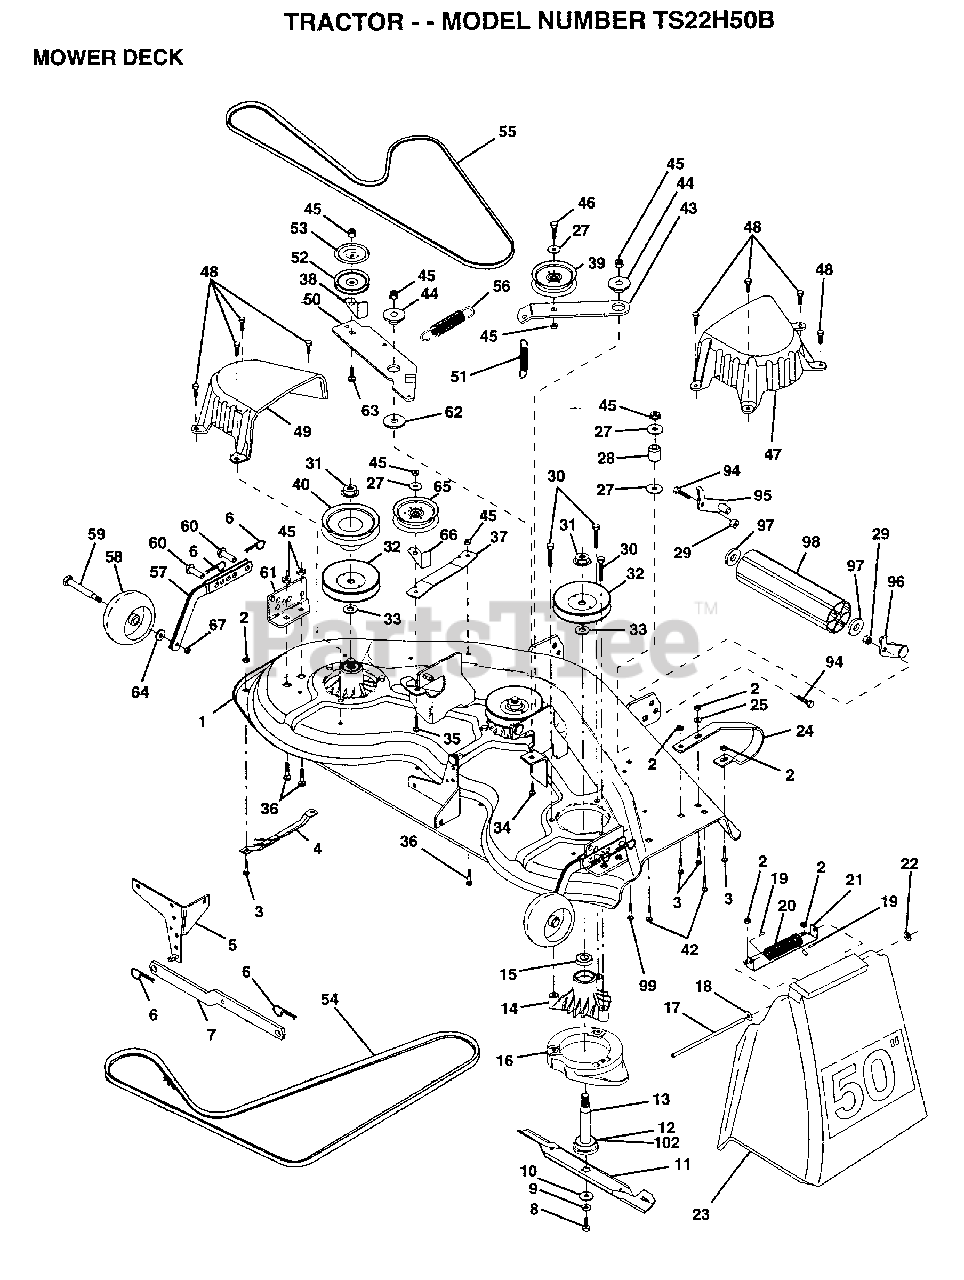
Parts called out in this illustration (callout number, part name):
1	Deck Asm., Mower 50" Vented
4	RUNNER-LH M
5	BRKT.ASM.SW.44/50
8	BLADE BOLT
10	WASHER.HARD.BLADE
11	"BLADE.50"" HD"
12	BEARING.BALL
13	SHAFT.ASM.W/BRNG
14	HOUSING.MAND.44.V
15	BEARING
16	STRIPPER RND MWR
17	ROD-HINGE T
18	WASHER
19	CAP-SLEEVE LT
20	SPRING TORSION
21	BRKT DEFLECTOR
22	NUT PUSH M
23	DEFLECTOR
24	"RUNNER RH 50"" DK"
25	WASHER M
27	WASHER
29	NUT
32	PULLEY.MANDREL.42
33	WASHER
34	BOLT.3/8-14X1.25
35	BOLT
36	BOLT D
37	STIFFENER.ARM.IDL
39	FLAT IDLER PULLEY
40	"PULLEY.DRIVEN.44"""
42	BOLT
43	"ARM.IDLER.SEC.44"""
44	SPACER RETAINER
47	"COVER.MAND.RH.44"""
48	SCREW.1/4-20X5/8
49	COVER.MANDREL.LH
50	ARM.IDLER.PRIMARY
51	"SPRING.SEC.44""VEN"
52	PULLEY.IDLER.VGRO
53	SHIELD.IDLER.44.V
54	BELT V PRIM 50
55	BELT-V.SEC.46.KEL
56	SPRING.EXT.DECK.
57	BAR.ASM.GUAGE.WHL
58	WHEEL.GUAGE.MED.
59	BOLT.SHOULDER
60	PIN.CLEVIS
61	BRACKET.GUAGE.WHL
62	HARDENED WASHER
63	BOLT.3/8-16X1.50
64	WASHER
65	PULLEY IDELR FLAT
67	LOCKNUT
94	BOLT
97	WASHER
99	BOLT
102	WASHER.FELT.
